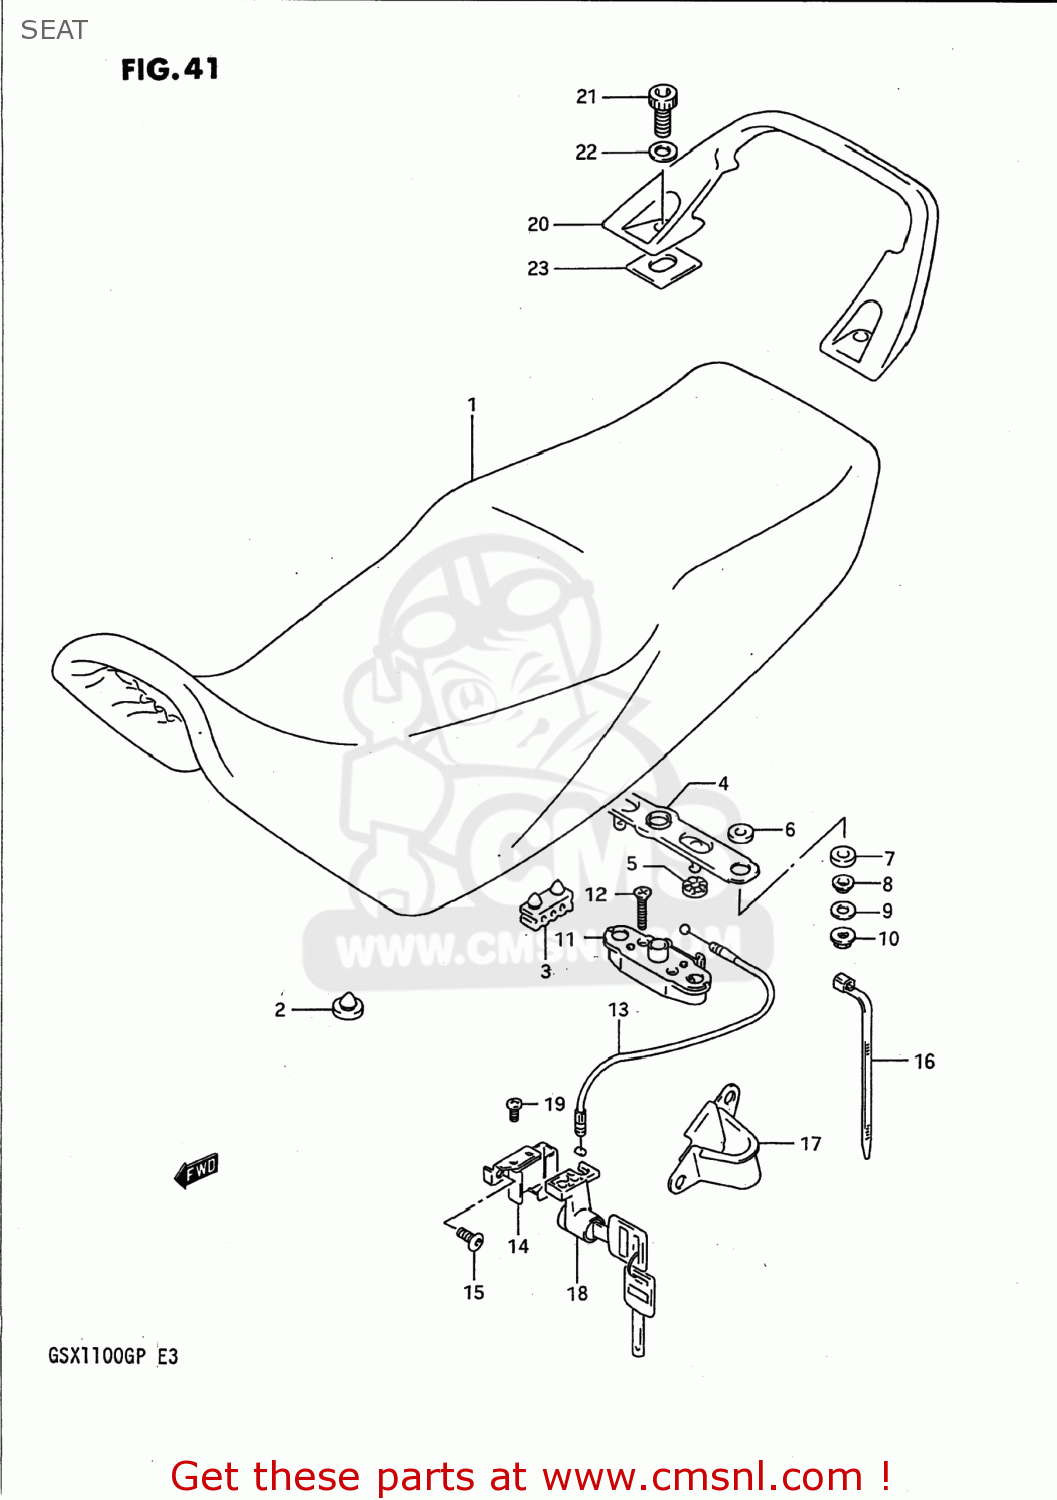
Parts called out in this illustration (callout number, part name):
1	SEAT ASSEMBLY
2	CUSHION
3	CUSHION,SEAT(40X20X15)
4	STRIKER,SEAT LOCK
5	CUSHION,SEAT LOCK(10X22X6)
6	CUSHION,UPR
7	CUSHION,LWR
8	WASHER
9	WASHER
10	NUT
11	BRACKET,SEAT SUPPORT,RIGHT
12	SCREW
13	CABLE COMP,SEAT LOCK
14	BRACKET,SEAT LOCK
15	SCREW
16	CLAMP(L:165)
17	PLATE COMP,SEAT LOCK C
18	LOCK SET,SEAT
19	SCREW
20	HANDLE,PILLION RIDER
21	BOLT
22	WASHER
23	CUSHION,FRAME COVER
